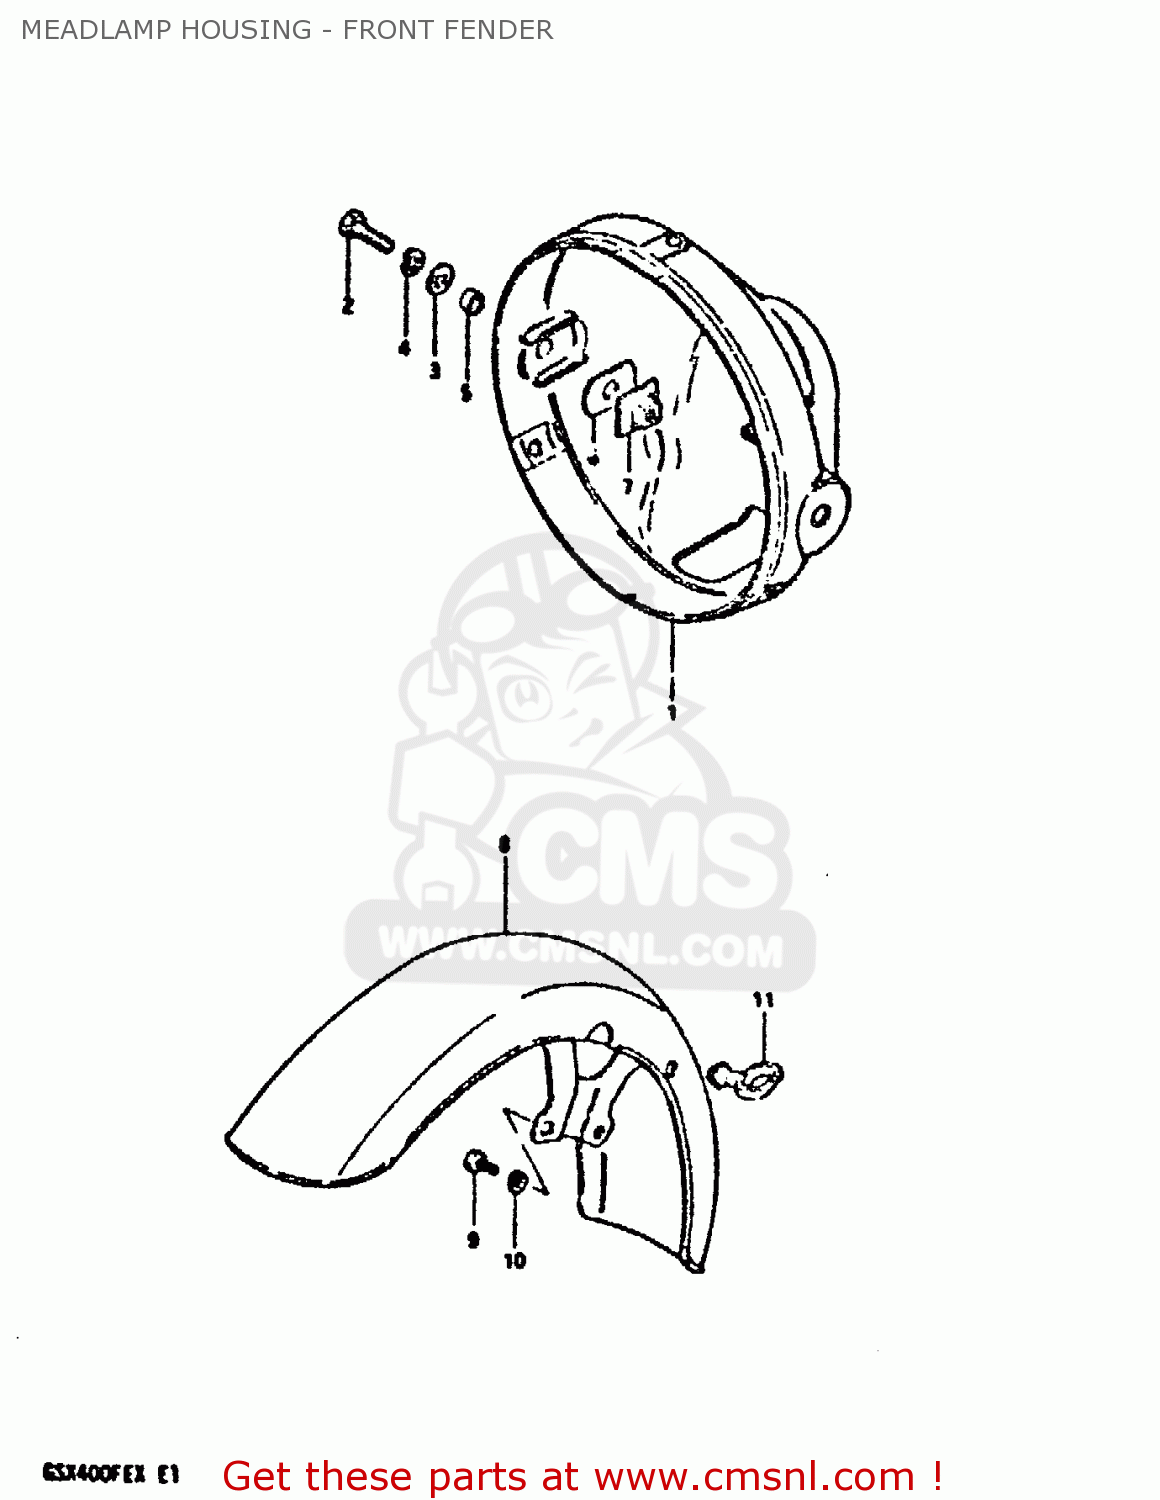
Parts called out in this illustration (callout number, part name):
1	HOUSING,HEADLAMP
2	BOLT
3	WASHER
4	LOCK WASHER
5	WASHER
6	CUSHION
7	PLATE
8	FENDER,FRONT
9	BOLT
10	LOCK WASHER
11	GUIDE,CABLE
